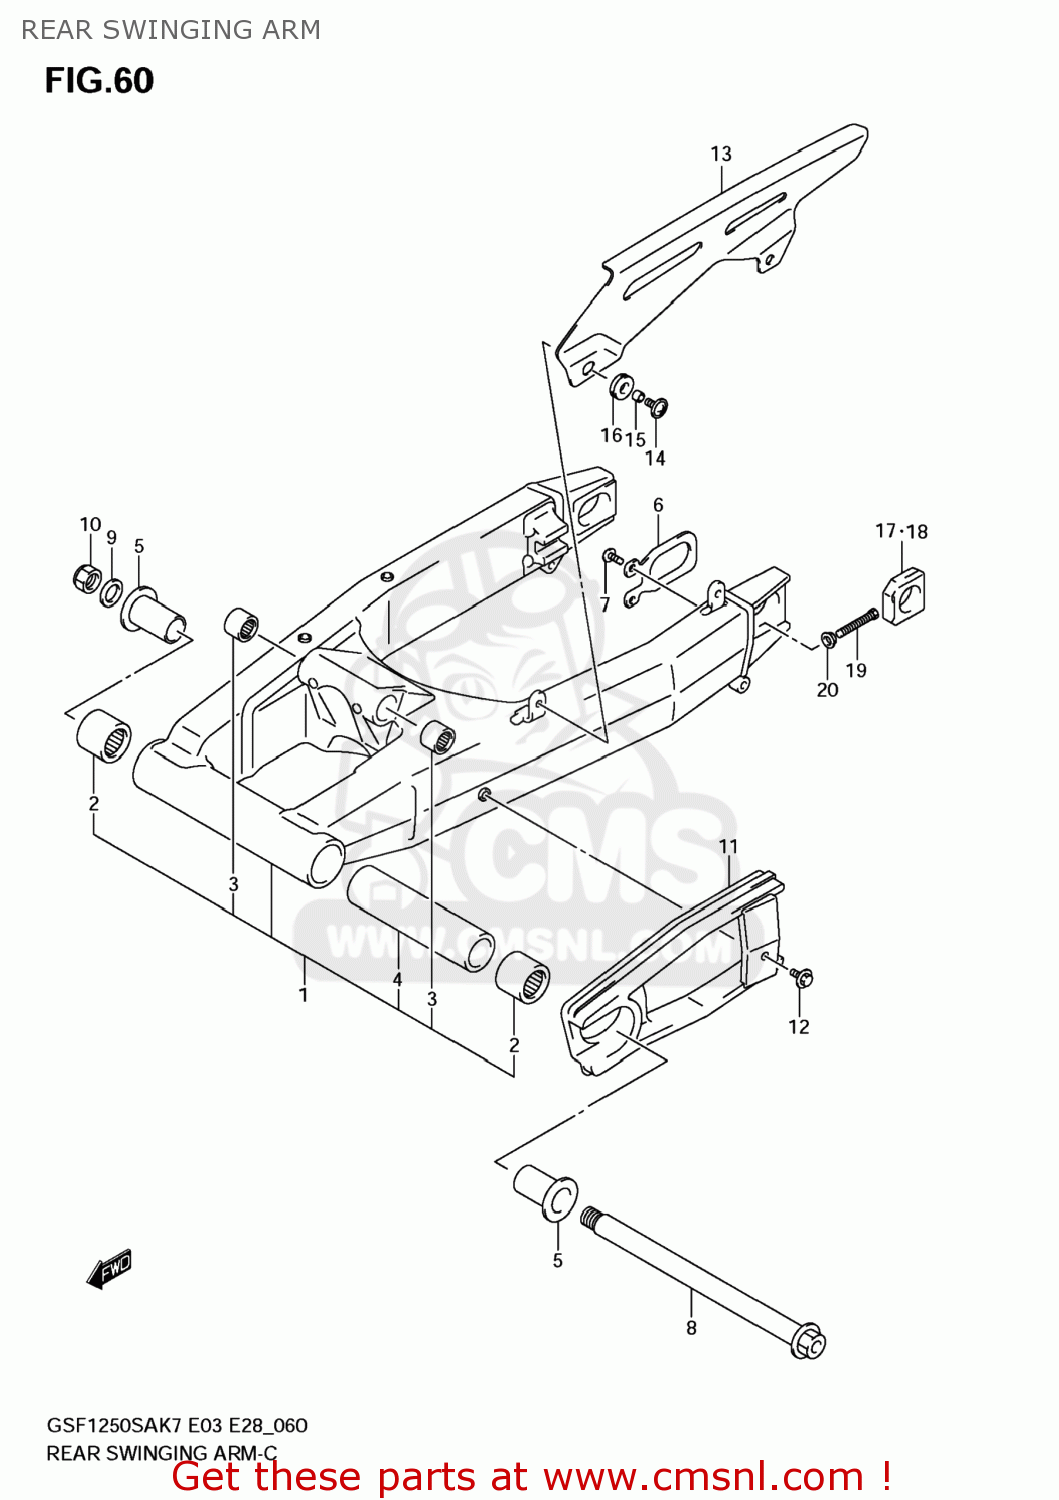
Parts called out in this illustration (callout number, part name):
1	SWINGINGARM ASSY,RR
2	BEARING(25X33X35)
3	BEARING(17X24X25)
4	SPACER,RR SWGARM PIVOT CTR
5	SPACER,RR SWGARM PIVOT BERRING
6	PLATE,RR SWING ARM BRKT
7	SCREW
8	SHAFT,RR SWINGINGARM PIVOT
9	WASHER(18.5X28X2.6)
10	NUT
11	BUFFER,CHAIN TOUCH DEFENSE
12	BOLT(6X17.8)
13	CASE,CHAIN
14	SCREW(6X16)
15	SPACER(6.2X8.3X6.1)
16	CUSHION
17	ADJUSTER,CHAIN
18	ADJUSTER,CHAIN
19	BOLT(8X50)
20	NUT
